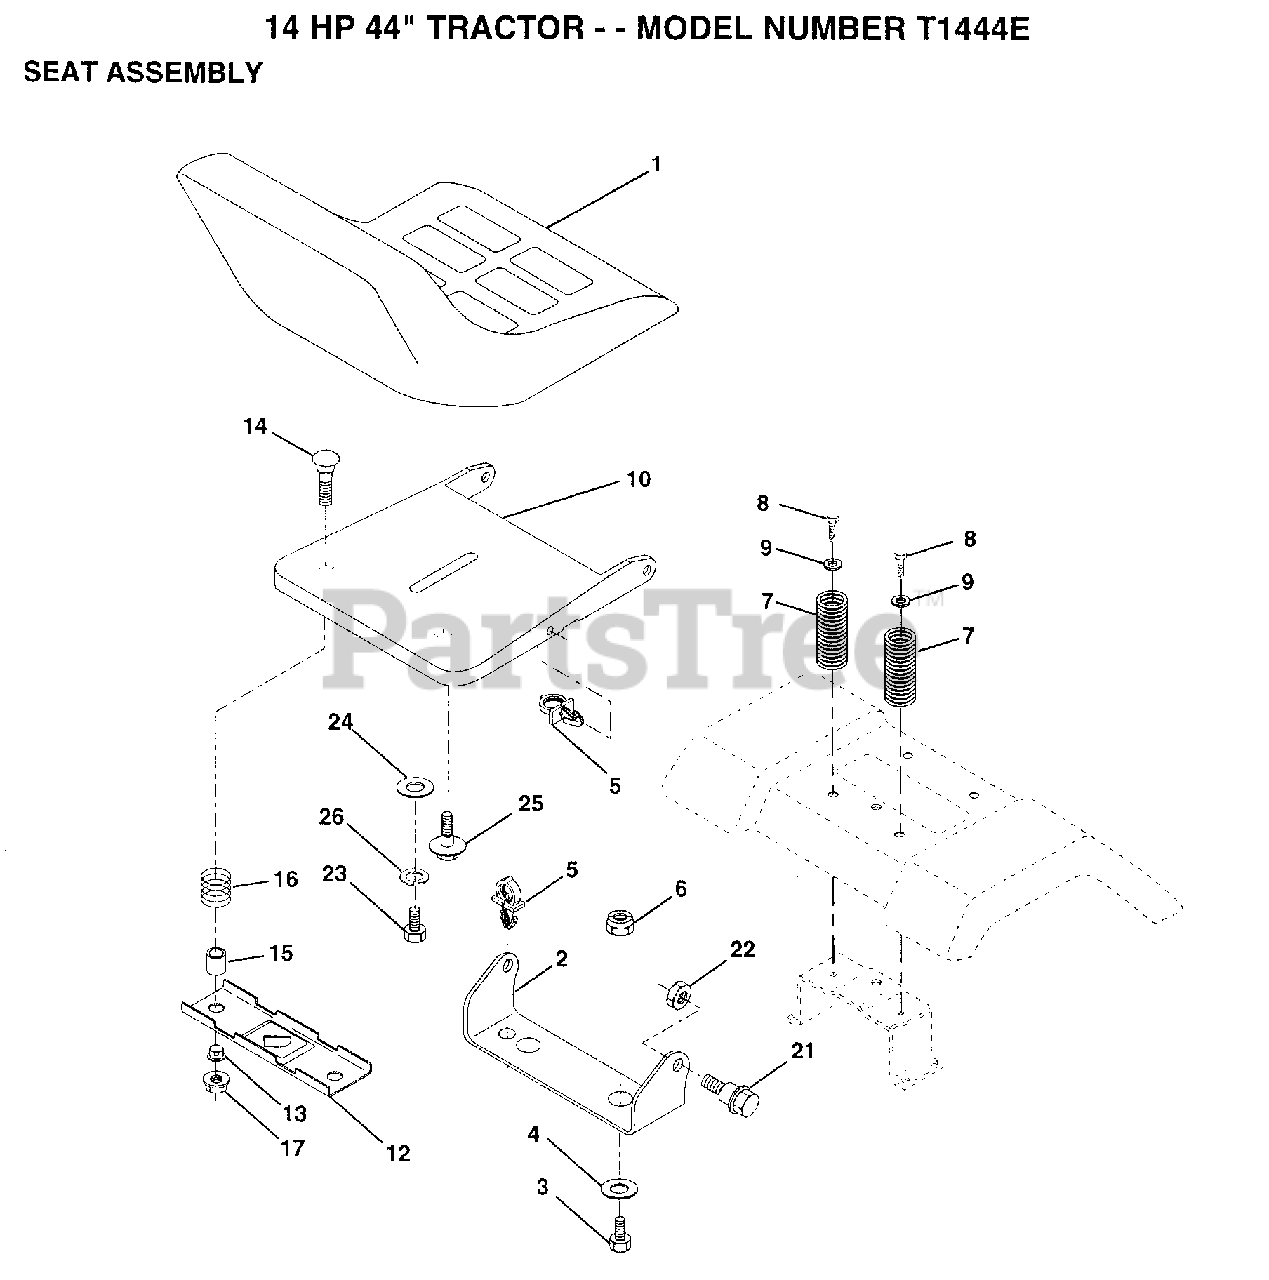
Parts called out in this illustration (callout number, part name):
2	BRACKET PVT SEAT
3	BOLT
4	WASHER PM
5	CLIP PUSH - IN
6	NUT
7	SPRING COMPRESSIO
8	SCREW GTV
9	WASHER
12	BRKT SWITCH
13	BUSHING
15	SPACER SPLIT
16	SPRING COMPRESSED
21	BOLT.SHLD.5/16-18
22	NUT
23	BOLT
24	WASHER
25	"BOLT,SHOULDER"
26	LOCKWASHER
